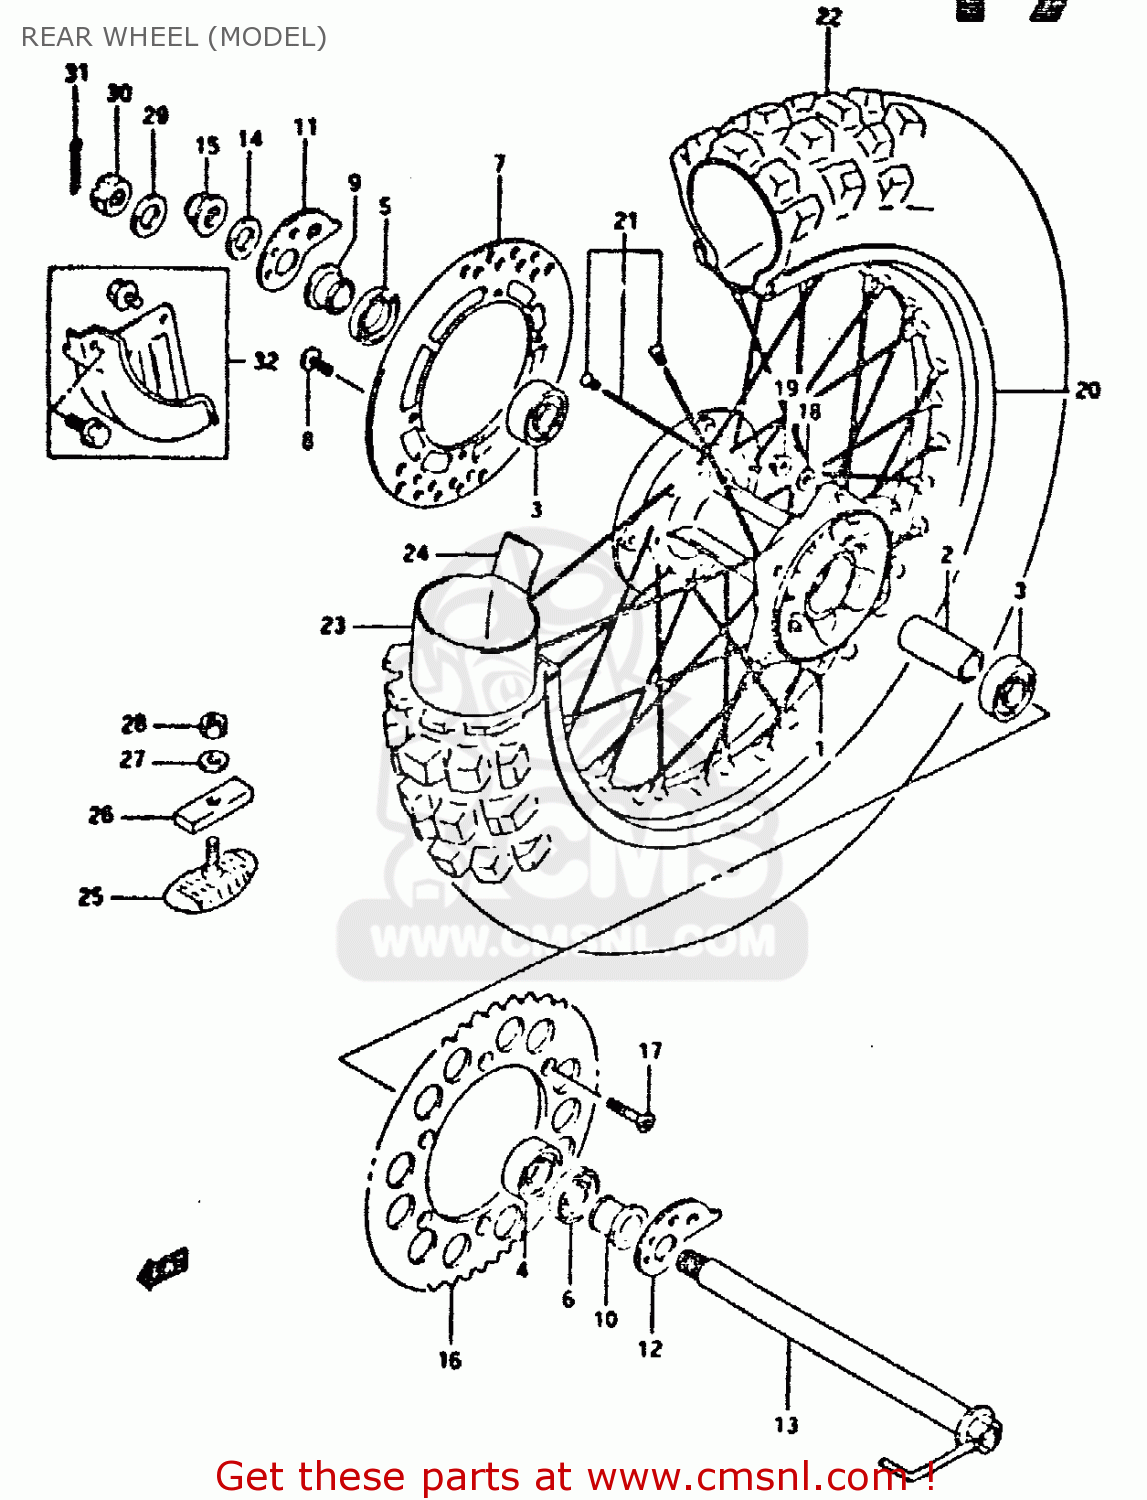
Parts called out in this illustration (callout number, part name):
1	HUB,REAR WHEEL
2	SPACER,RR HUB BEARING
3	BALL BEARING
4	BEARING
5	SEAL,OIL(26X42X8)
6	SEAL,OIL(26X47X5)
7	DISC,RR BRAKE
8	BOLT
9	SPACER,RR AXLE,R
10	SPACER,RR AXLE,L
11	ADJUSTER,CHAIN,R
12	ADJUSTER,CHAIN,L
13	AXLE,RR
14	WASHER(19X32X3.2)
15	NUT 18MM
16	SPROCKET,RR(NT:43)
17	SCREW(8X33.5)
18	WASHER
19	NUT
20	RIM,RR WHEEL(18X2.15 AL)
21	SPOKE SET,RR WHEEL
22	TIRE COMP,REAR 110/100-1
23	TUBE,INNER
24	PROTECTOR,INNER TUBE
25	STOPPER,BEAD
26	CUSHION,BEAD STOPPER
27	WASHER
28	NUT
29	WASHER(19X32X3.2)
30	NUT
31	PIN,COTTER
32	COVER SET,RR BRAKE DISC
